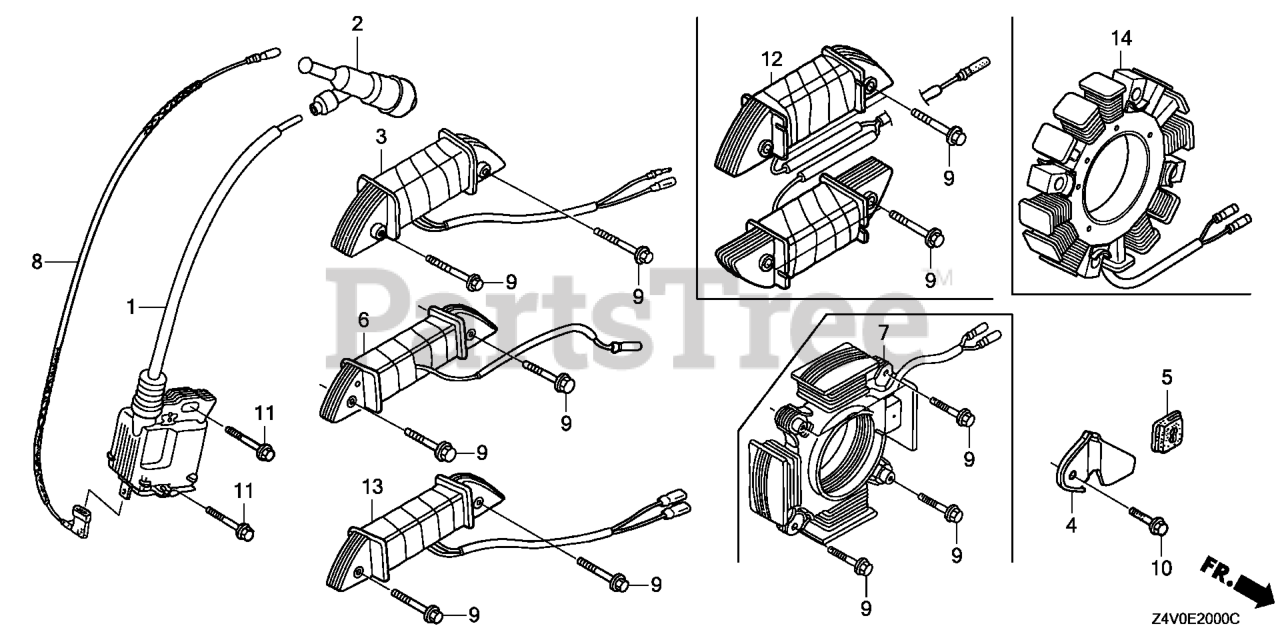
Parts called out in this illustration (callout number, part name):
1	COIL ASSY., IGNITION (TEC)
2	CAP ASSY., NOISE SUPPRESSOR (TEC)
4	CLAMP, WIRE
5	GROMMET, WIRE
6	COIL ASSY., CHARGE (1A)
8	WIRE, STOP SWITCH (395MM) Use from Engine SN 3155569.
9	BOLT, FLANGE (6X28) (CT200) Use up to Engine SN 1530314.
10	BOLT, FLANGE (5X10)
11	BOLT, FLANGE (6X25) Use up to Engine SN 2056819.
